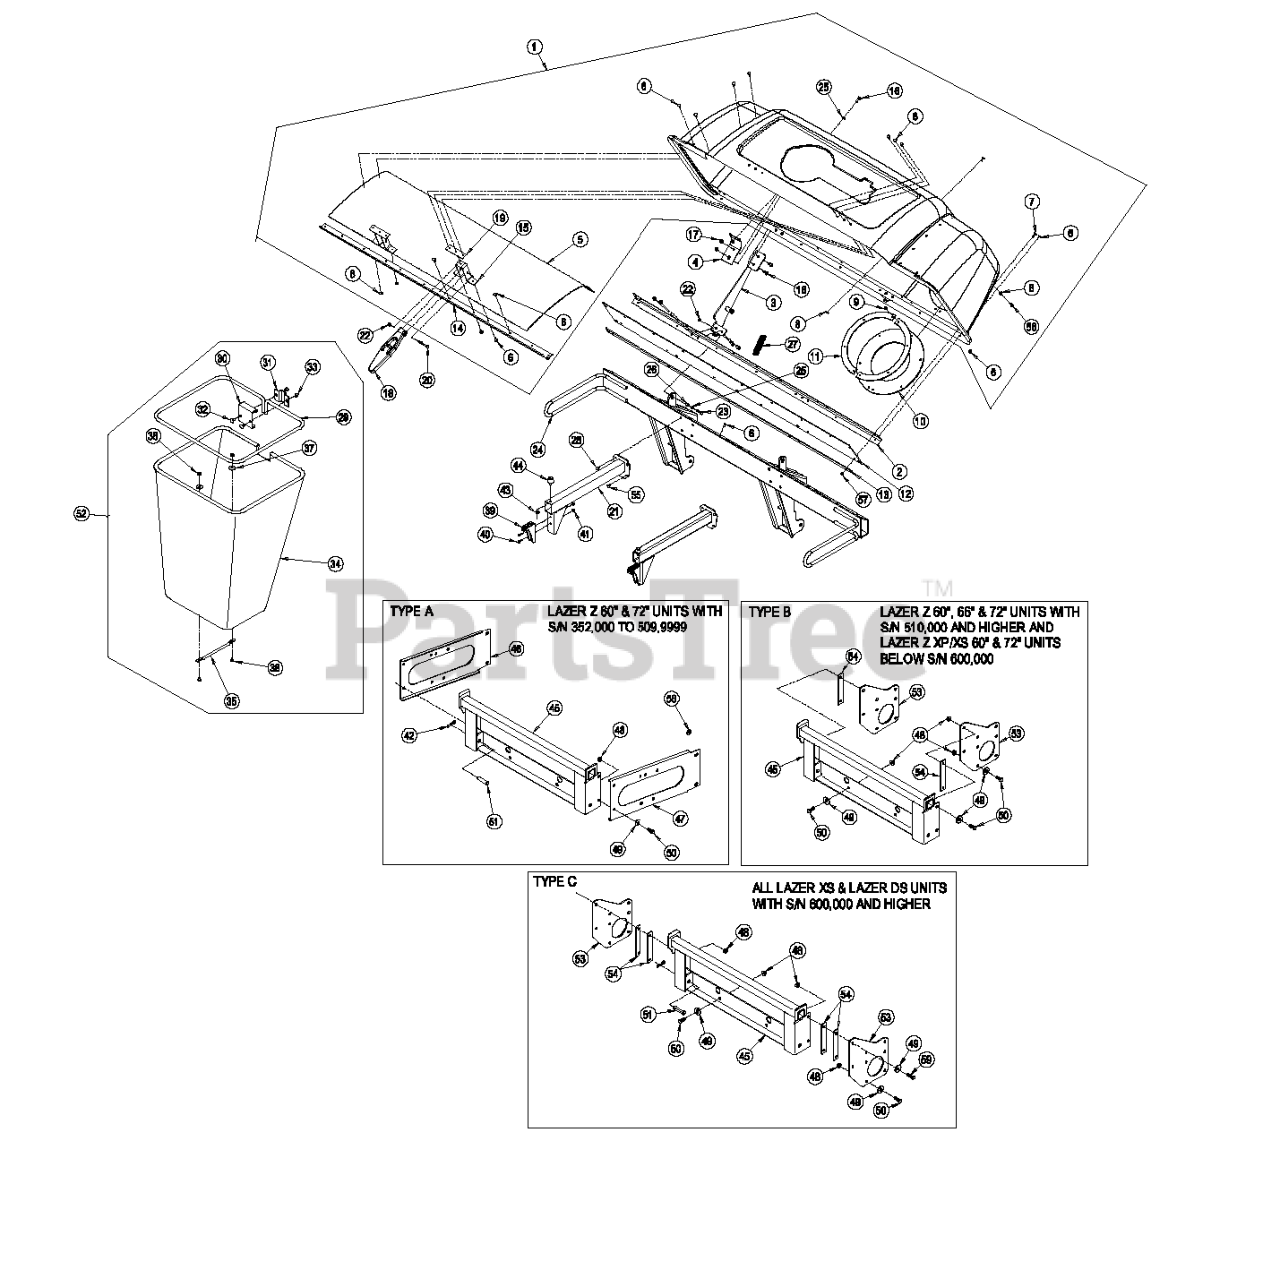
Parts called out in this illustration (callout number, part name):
1	Asm, Hood
2	Stiffener, Bagger Top
3	Wld Hinge
4	Reinforcement, Hood
5	Screen, Bagger
6	Rivet, Pop 3/16 x 1/2
7	Screw, Truss HD #10-24 x 3/4
8	Washer, 216 x 750 x 049
9	Nut, Nyloc #10-24
10	Seal, Tube
11	Clamp, Seal
12	Seal, Hinge
13	Plate, Backing
14	Support, Screen
15	Bracket, Mount
16	Screw, HH 1/4-20 x 3/4
17	Nut, Whizlock 1/4-20
19	Plate, Latch Reinforcement
20	Screw, HH 1/4-20 x 2
21	Wld, Bag Support
22	Nut, Nyloc 1/4-20
23	Screw, HH 1/4-20 x 1
24	Wld, Bagger Upright
25	Washer, 1/4 Std
28	Screw, HH 5/16-18 x 3/4
29	Frame, Bag
30	Hanger, Bag
32	Bolt, Carriage 5/16-18 x 3/4
33	Nut, Nyloc 5/16-18
34	Bag, Cloth
35	Handle, Bag
36	Bolt, Carriage 1/4-20 x 3/4
37	Washer, 344 x 175 x 062 Pltd
38	Nut, Nyloc 1/4-20
40	Screw, PPH #10-24 x 5/8
41	Nut, Whizlock #10-24
42	Hairpin
43	Nut, Whizlock 1/4-20
45	Wld, Bagger Mount
46	Bracket, Frame LH (Type A)
47	Bracket, Frame RH (Type A)
48	Nut, Whizlock 3/8-16 (Type A)
48	Nut, Whizlock 3/8-16 (Type B & C)
49	Washer, Spring Disc 3/8 (Type A)
50	Washer, Spring Disc 3/8 (Type B & C)
50	Screw HH 3/8-16 x 1 1/4 (Type A)
50	Screw HH 3/8-16 x 1 1/4 (Type B)
50	Screw HH 3/8-16 x 1 1/4 (Type C)
51	Clevis Pin
52	Asm, Bag
53	Plate, Bagger Mount (Type B & C)
54	Spacer (Type B)
54	Spacer (Type C)
55	Screw, HSBH 5/16-18 x 3/4
56	Screw, PPH #10-24 x 7/8
57	Nut, Side Lock #10-24
58	Spacer, ROPS (Type A)
59	Screw 3/8-16 x 125 (Type C)
